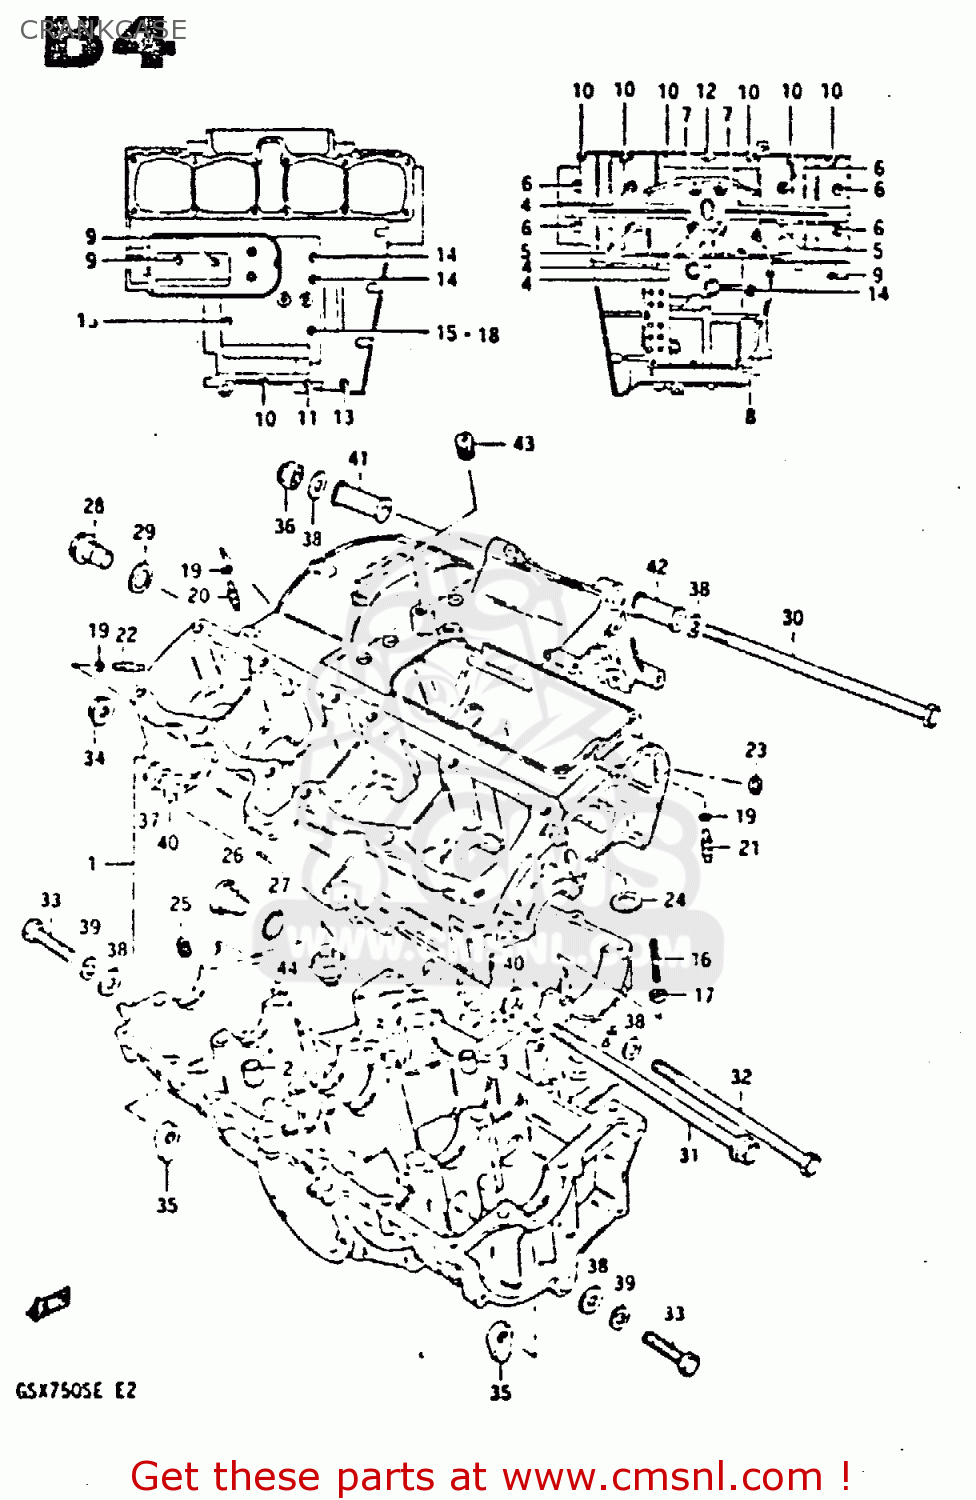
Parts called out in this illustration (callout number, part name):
1	CRANKCASE ASSEMBLY
2	PIN(10.4X13X22)
3	PIN (11X20)(SUS)
4	BOLT(8X120)
5	BOLT(8X135)
6	BOLT
7	BOLT
8	BOLT 8X60
9	BOLT 6X35
10	BOLT
11	BOLT
12	BOLT 6X50
13	BOLT 6X55
14	BOLT
15	BOLT (5X95)
16	STUD BOLT (6X45)
17	NUT
18	GASKET(6.2X13X1.2) (NAS)
19	O RING(D:1.2,ID:4)
20	JET,OIL GALLERY
21	JET(8)
22	JET,OIL
23	O RING(D:3.2,ID:12.9)
24	WASHER,THRUST
25	JET,AIR
26	PLUG
27	O RING(D:2.4,ID:16.8)
28	PLUG
29	GASKET(14X19.2X2) (NAS)
30	BOLT 10X255
31	BOLT 10X205
32	BOLT
33	BOLT
34	NUT 10MM
35	NUT
36	NUT
37	NUT
38	WASHER
39	LOCK WASHER
40	WASHER (10.5X22X2.3)
41	SPACER,ENGINE MOUNT
42	SPACER,ENGINE MOUNT(L:50)
43	PLUG
44	SWITCH ASSEMBLY
